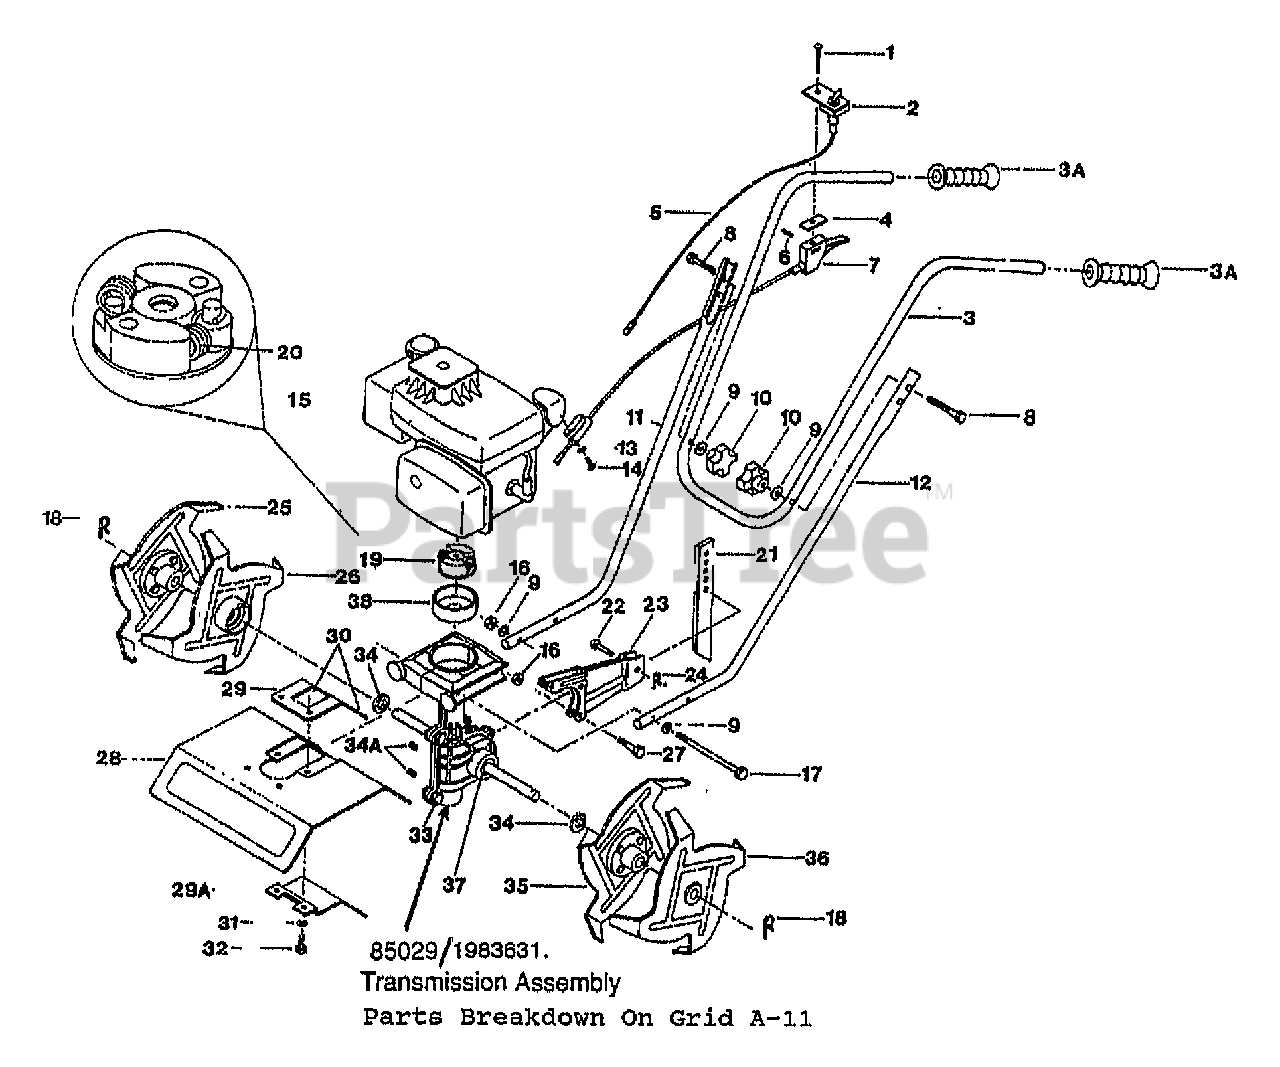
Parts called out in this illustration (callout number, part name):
1	SCR-PH HD M10-24X1.375
2	SWITCH-IGN. 96506
2	BRKT-SWITCH PNT
3	ASSM-UPR HANDLEBAR
3A	GRIP-HANDLEBAR 97030
4	PAD-ISOLATOR TRIGGER
5	HARNESS-WIRE
6	NUT-WELD #10-24
7	CABLE-THROTTLE MINITILLER
8	SCR-CURVED HD 5/16-18X2.0
9	WASHER-FLAT 5/16 SAE
11	H/BAR-LWR RIGHT PNT
12	H/BAR-LWR LEFT PNT
13	WASHER-.44X.187X.05
14	SCR-HH M8-32X1.0
15	ENGINE, TECUMSEH TC-200-2106
16	NUT-LK 1/4-20
17	SCR-HH 1/4-20X5
18	PIN-HITCH .149DIA
19	KIT-ROTOR ASSM
20	KIT-ROTOR ASSM
21	DRAGSTAKE-PNT
22	PIN-CLEVIS
23	BRKT-WHEEL ASSM PNT
24	CLIP-HAIRPIN .07 DIA
25	ASSM-TINE OUTER RH
26	ASSM-TINE INNER RH
27	SCR 1/4-20X1.125 (DRAG STAKE TRANSMISSION)
28	HOOD W/DECAL 85056 SPEEDYHOE
29	HOOD-FILL PIECE MINI PNT
29A	SHIELD-ROCK PNT
30	SCR M10-32X.375 STH (FOR REAR TINE COVER PLATE)
31	WASHER-LK .25
32	SCR-HH 1/4-20X2.0 G5
33	SCR-HH 1/4-20 X .875
34	WASHER-FELT 1.5X.72X.13
34A	SCR M10-32X.25
35	ASSM-TINE INNER LH
36	ASSM-TINE OUTER LH
37	KIT-DUST CAP
37	SCR M10-32X.25
38	CLUTCH-DRUM & HUB
